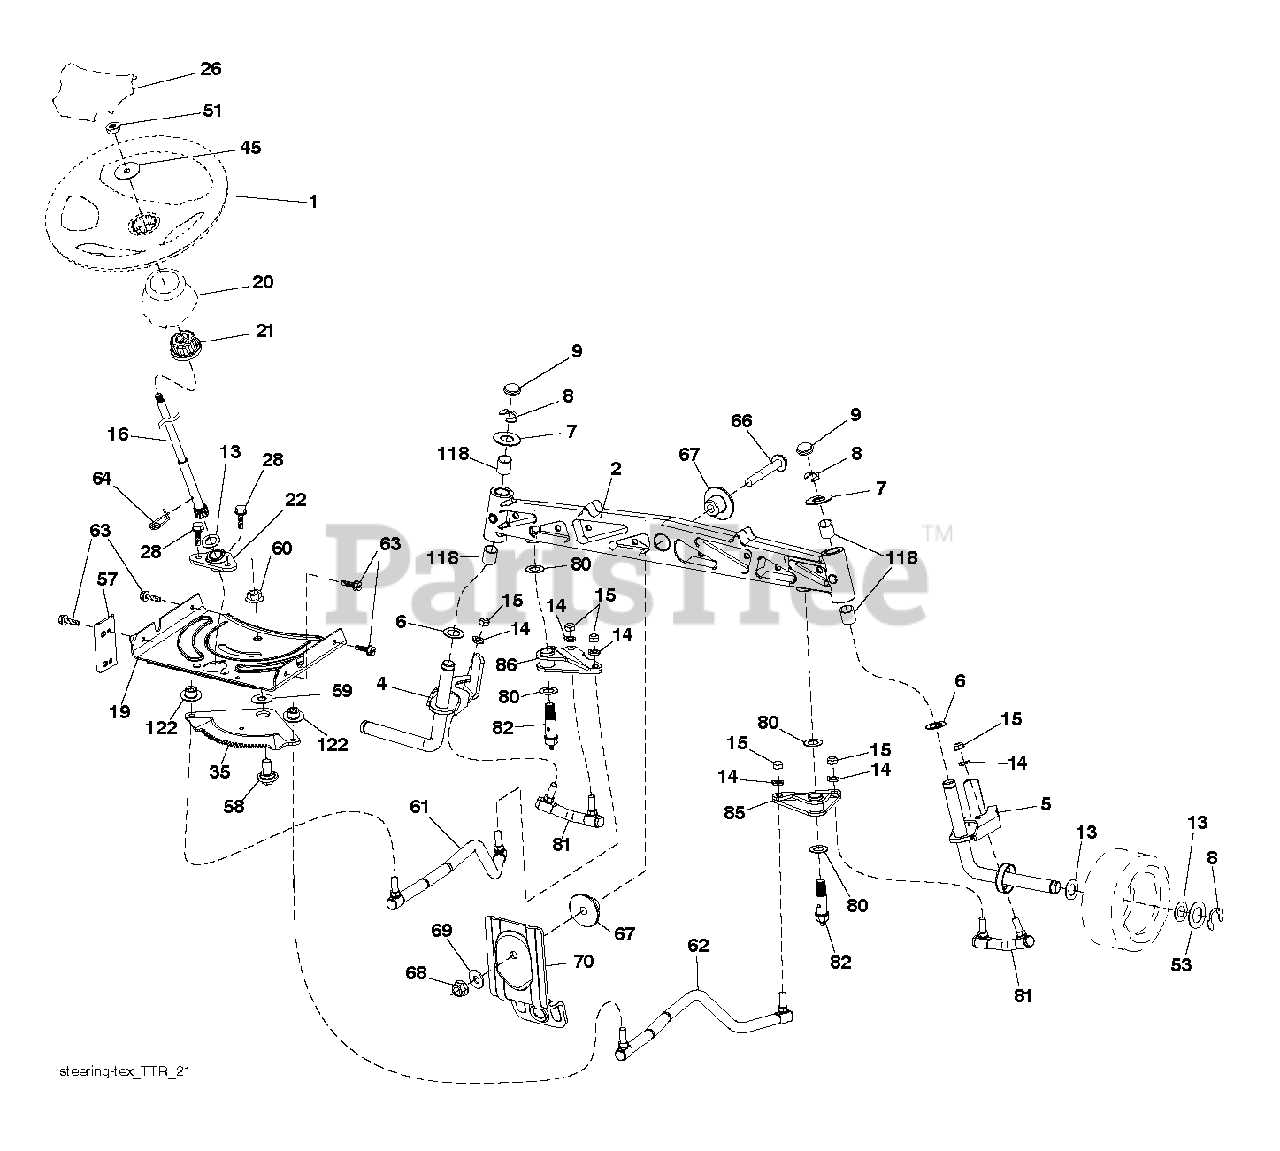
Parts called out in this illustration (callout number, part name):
1	WHEEL.STEERING.STDSRR.BLK/OV
8	RING CLIP
9	CAP.SPINDLE
14	WASHER, LOCK 3/8
15	NUT CROWNLOCK 3/8-24
19	PLATE.STEER.DDL.NLT/NG
21	STEERING.WHEEL.ADAPTER
22	BUSHING.ASM.STEERING.A
26	CAP.WHL.STRNG.STDSRRD.SRS.BLK
28	SCREW, 3/8-16X3/4
45	WASHER 9/16"ID, 2 3/8"OD
51	NUT.HEX.1/2-20
53	WASHER.HARDENED
57	BRACKET.UPSTOP.TEX
58	BOLT.SHOULDER.SECTOR.P
59	WASHER.THURST.SECTOR.S
60	NUT FLANGE LOCK 5/8-11
63	SCREW
64	RETAINER.CLIP.SPRING.S
66	BOLT HEX FGHD 7/16-14 X 3 SERR
67	BUSHING.PM.FRONT AXLE
68	NUT.LOCK.FLANGE.7/16
69	WASHER.1.5X.505X.118
70	BRKT.DECK.SUSPENSION.F
80	THRUST WASHER
118	BUSHING, AXLE CAST
